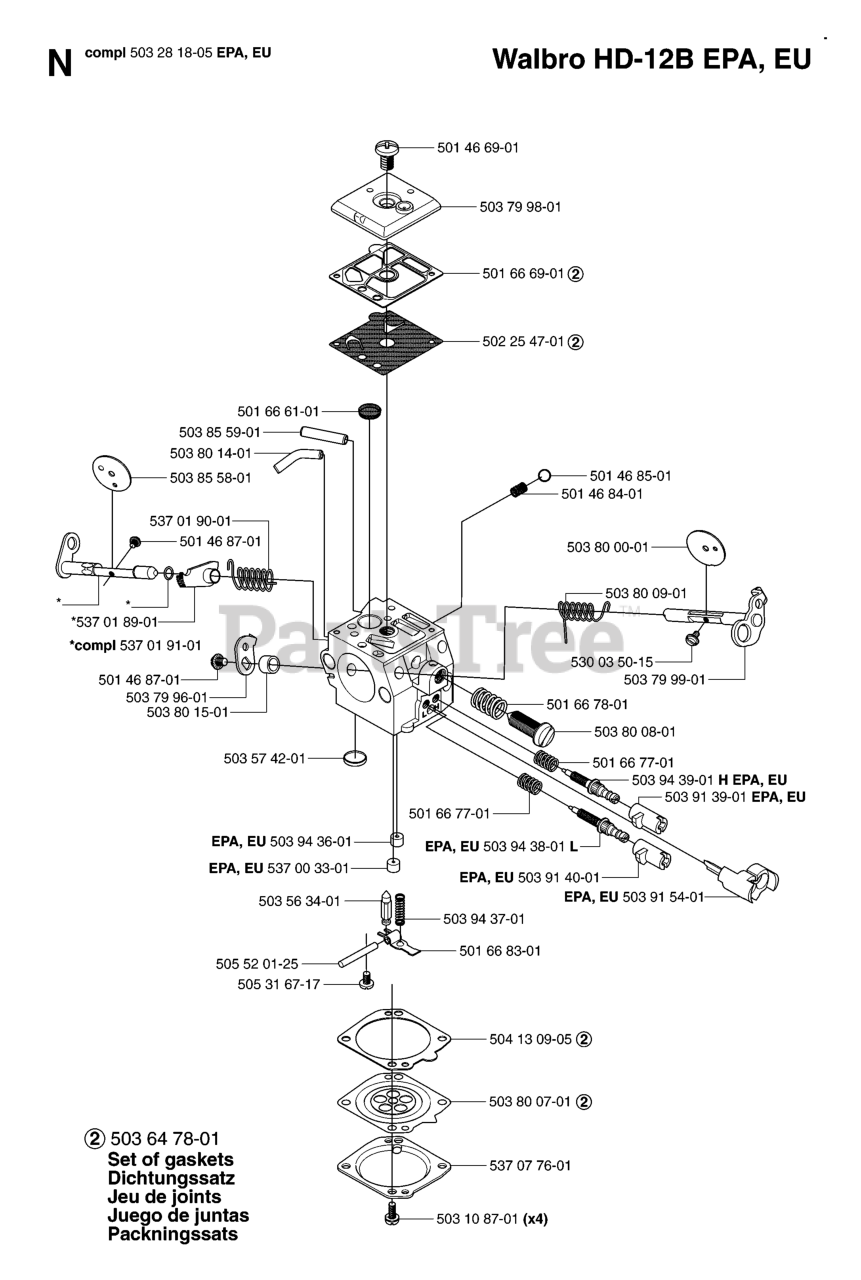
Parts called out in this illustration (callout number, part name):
1	CYLINDR.HEAD.SRV.KIT W/GASKET
2	KIT.PUSH.ROD.SRV(SK208-1001)
3	VALVE COVER ASSEMBLY
5	KIT.PISTON.SRV(SK208-1400)
6	KIT.CONNECT.ROD.SRV(SK208-1500
7	KIT.CAMSHAFT.208CC.LCT
8	208CC ELEC START FLYWHEEL
9	FLYWHEEL FAN 420586
10	CRNKSHFT-KYD#14.208CCSKSNO8001
13	MUFFLER KIT LCT SKSN2205.1
14	FUEL.TK.ASSY.GENII.SKSN0311.1
15	FUEL.PETCOCK.SNOW(SKSN4900)
16	FUEL CAP OVERSIZED CLICK STYLE
17	CARBURETTOR L10-1D.W/SP
18	208CC IGN COIL (STD)
20	SPARK.PLUG(2083810)
21	SWITCH.ON/OFF(SKSN-0403)
22	SHLD.ELEC.START.FLY(SKSN-0605)
23	FUEL HOSE KIT
24	SPEED.CTRL.BRKT.(SKSN0150)
25	GOVENOR.GEARS ASM(SK2082900)
26	CARBURETTOR GOVERNOR LINK.ASM.
27	KIT.GOVERNOR.CRANK(SK208-3100)
28	RECOIL.STRT.ROUND(BLK) SNOW
29	STRTER.CUP(NON-SLOT)SKSN0601.2
30	BLOWER.HOUSING.ELEC.START.LCT
31	COVER.CRANKCASE.LCT.HIGH.OIL.F
32	SEAL KIT (2 PCS)
34	SPARK.PLUG.BOOT.SNW,SKSN4691.1
35	STARTER.EL.230C.SNO.LCT.208CC.
36	GASKET.KIT.208CC(SK2084300.1)
37	DIPSTICK SMALL
38	ROCKER ARM KIT
39	CHOKE.KNOW.SNOW(SKSN4500)
40	NON REMOVABLE PLUG
43	TUBE.BREATHER.LCT.208
47	TUBE ASSY HIGH OIL-FILL
48	WIRE.HARNESS.SNOW
49	KIT.OIL.DRAIN.PLUG(SK2089911
50	HEATER.BOX.ASY-GEN2
51	SHIELD.CYLINGER.LCT.SKSN0608.1
52	PRIMER.BULB.WITH HOSE (SNOW)
53	SWITH.KEY.ASSEM.SNOW.SINGLE.ST
54	KEY SET(2 KEYS) SKSN0407.1
55	OIL PIPE DRAIN LCT 254
56	SHIELD.VAPOR.SNOW
58	GOVERNOR.LINK.SHIELD PLATE
59	FUEL.TNK.SKRT.GENII.SKSN0103.1
60	208CC 60W ALTERNATOR
61	FUEL KNOB-SNOW
62	STARTER.GRIP.SNOW.LCT.SKSN0603
65	TAPPET.KIT.LCT.208CC
69	CARB.STUDS & COUPLING KIT.SNOW
70	CARB.REPAIR.KIT.LCT.SK9900.2
72	KIT.ENGINE.DECAL.208CC.LCT.SK1
74	MUFFLER GUARD.EUR./LCT.SKSN220
77	BOLT.KIT.RECOIL.LCT.ALL.ENGINE
79	COVER.CARBURETOR.SNOW
81	KEYS.FLYWHEEL.208/414CC.5PACK
82	SPACER.CARBURETOR.208CC.LCT
85	STRAINER.FUEL.TANK.LCT.208CC
86	KIT.BOLT.CYLINDER.HEAD.(4PC)
87	KIT.BOLT.CRANKCASE.COVER.6PC
88	STUD.MUFFLER.KIT.LCT
89	KNOB LCT.SKSN5325.1 SPEED
91	COVER CRANKCASE GASKET
9999	HIGH.ALTITUDE.JET 6,000FT
